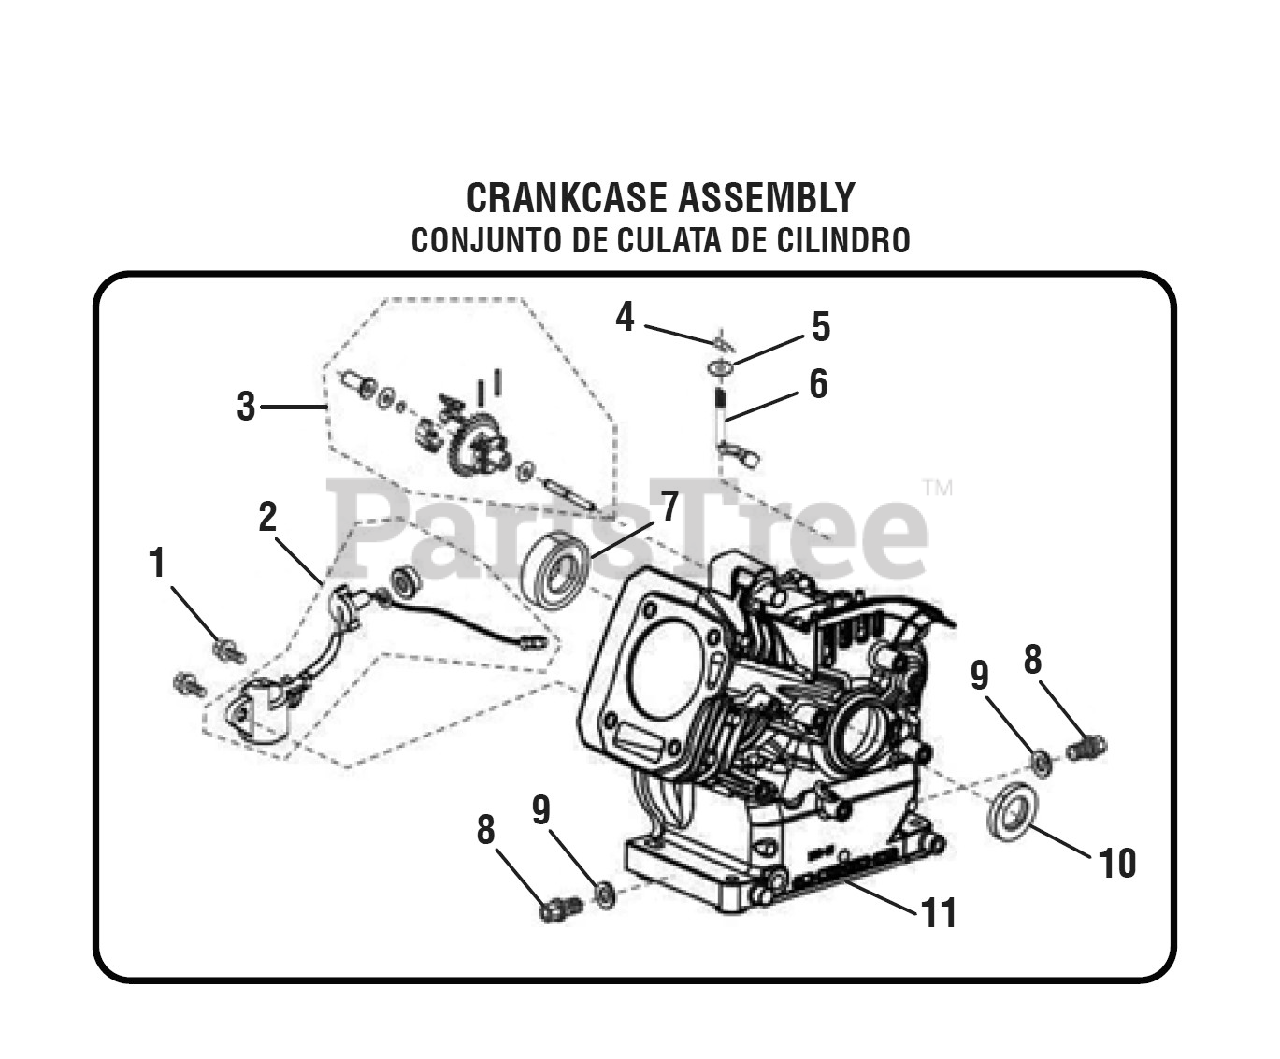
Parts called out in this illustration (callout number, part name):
2	Engine Oil Sensor
3	Governor Gear Assembly
4	Pin
5	Washer
6	Governor Arm
7	Ball Bearing
8	Drain Plug
9	Washer
10	Oil Seal
11	Crankcase Assembly
